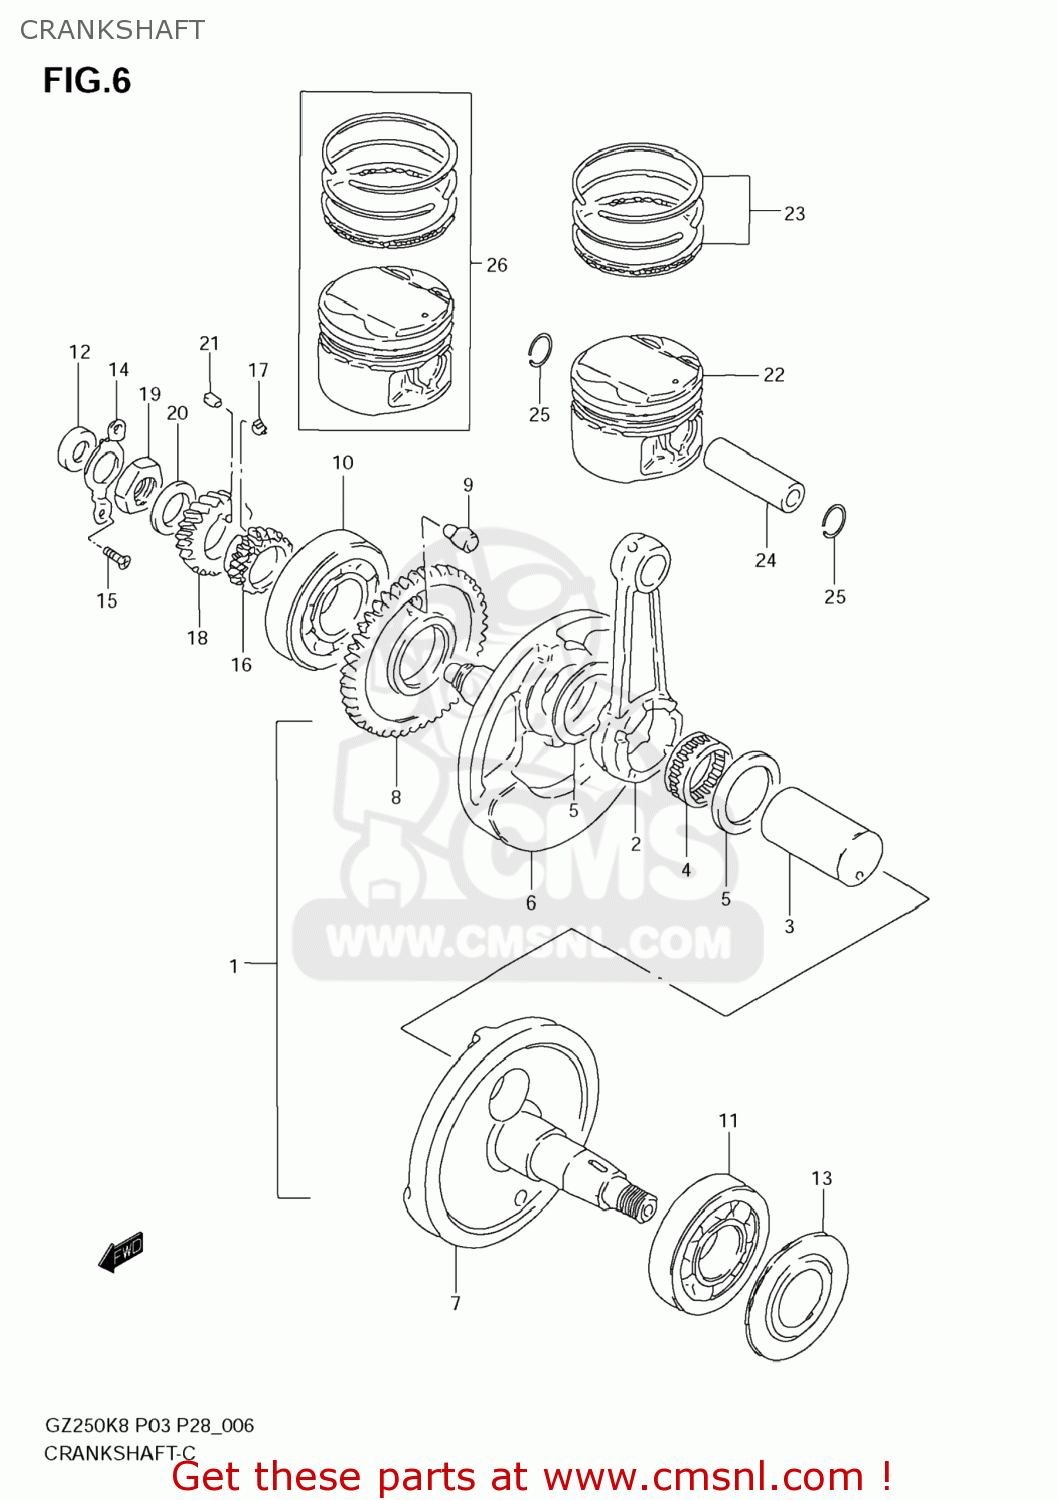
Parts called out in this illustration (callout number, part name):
1	CRANKSHAFT ASSY
2	ROD,CONNECTING
3	PIN,CRANK
4	BEARING(31X39X21)
5	WASHER(31X48.5X1)
6	CRANKSHAFT,R
7	CRANKSHAFT,L
8	GEAR,CRANK BALANCER DRIVE
9	PIN
10	BEARING
11	BEARING(35X80X21)
12	SEAL,OIL(14X26X6)
13	WASHER,CRANKSHAFT OIL SEALING
14	RETAINER,CRANKSHAFT BEARING,R
15	SCREW
16	SPROCKET,CAM CHAIN DRIVE(NT:21
17	KEY,SPROCKET
18	GEAR,PRIMARY DRIVE NO.21
19	NUT (20MM)
20	WASHER
21	KEY
22	PISTON
23	RING SET,PISTON
24	PIN,PISTON
25	CIRCLIP
26	PISTON SET(OS:0.5)
